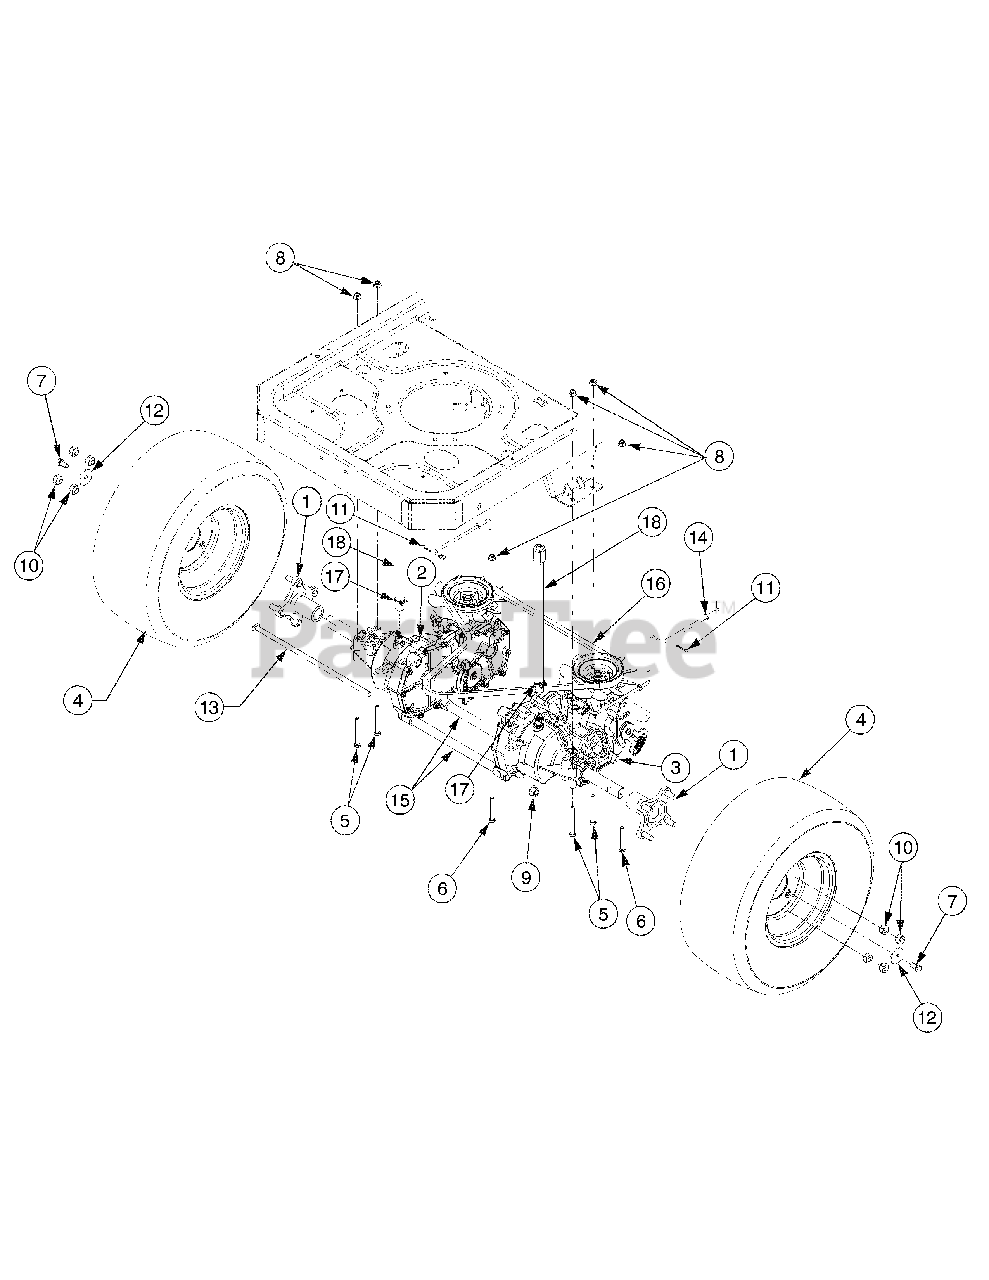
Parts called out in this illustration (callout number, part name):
1	Wheel Hub
2	Transmission Ass'y, LH
3	Transmission Ass'y, RH
3	Trans mission Ass'y, RH
4	Wheel Assembly 18 x 8.5 x 8 - Grey
4	Wheel Assembly 18 x 8.5 x 8 - Yellow
4	Wheel Assembly 18 x 9.5 x 8 - Grey
5	Hex Scr 5/16-18 x 2.75
6	Hex Bolt 5/16-18 x 2.25
7	Hex Cap Lock Scr. 3/8-16 x .75 Gr. 5
8	Flange Locknut 5/16-18 Gr. F, Nylon
9	Flange Lock Nut, 7/16-20
10	Lug Nut, 7/16-14
11	Cotter Pin 3/32 x .75
12	Flat Washer .39 ID x 1.5 OD x .135
13	Rod, .405 x 14.0
14	Rod, Bypass
15	Tube, .45 x .69 x 10.2
16	V-Belt, Type A Sec x 57.7
17	Hose Clamp
18	Hose, Breather
